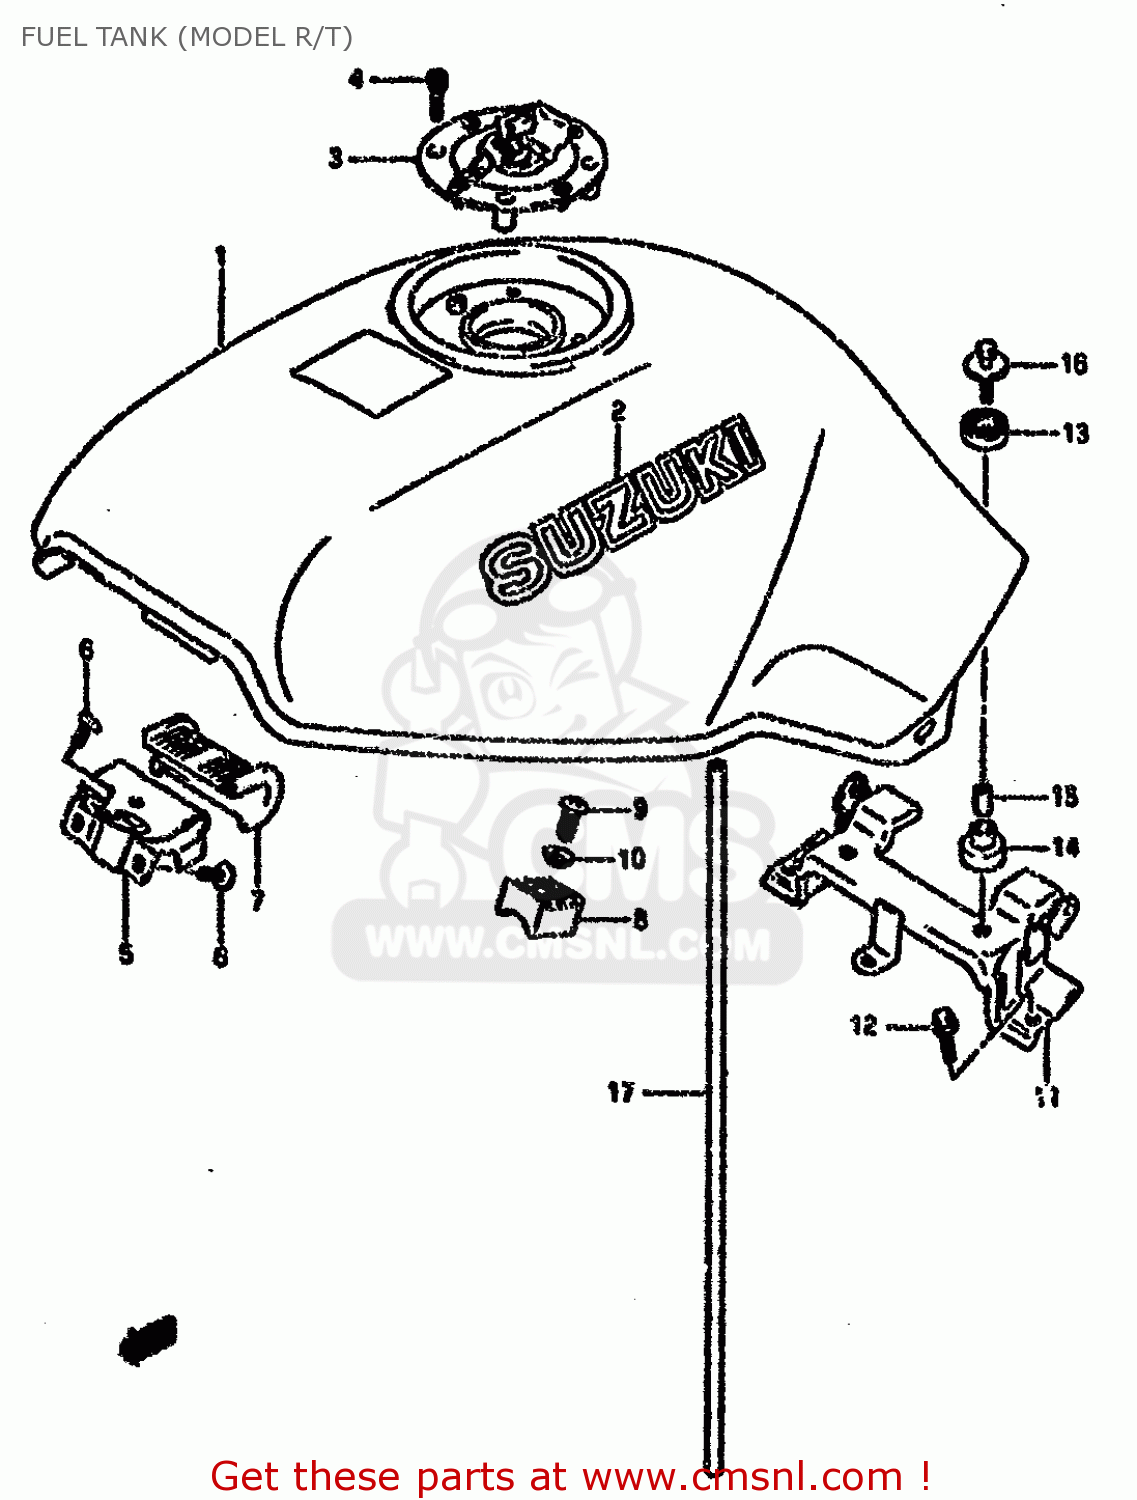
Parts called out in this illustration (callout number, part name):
1	TANK ASSY,FUEL (PURPLE)
2	EMBLEM,FUEL TANK
3	CAP SET,FUEL TANK
4	BOLT(5X20)
5	BRACKET,FUEL TANK FR
6	SCREW 6X12
7	CUSHION,FUEL TANK FR
8	CUSHION,FUEL TANK SIDE
9	SCREW
10	WASHER
11	BRACKET,FUEL TANK RR
12	BOLT
13	CUSHION
14	CUSHION
15	SPACER
16	BOLT
17	HOSE(5X8.2X600)
